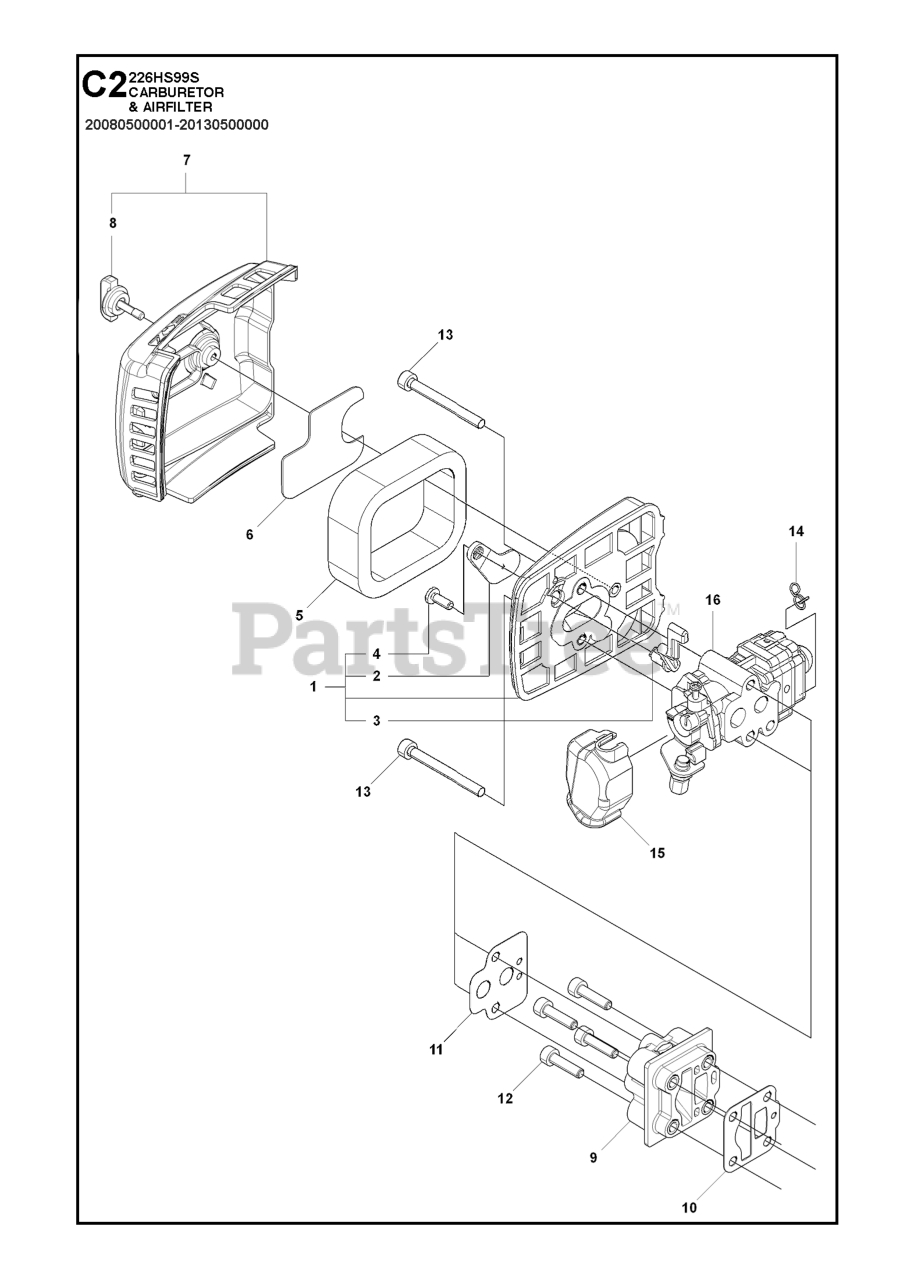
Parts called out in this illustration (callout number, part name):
2	PLATE, choke
4	SCREW
7	COVER ASSY
8	KNOB
9	%INSULATOR
10	GASKET, INSU
11	GASKET, CARB
13	BOLT TORX M5XL50 T27
14	CLIP
15	COVER
16	CARBURETOR ASSY
